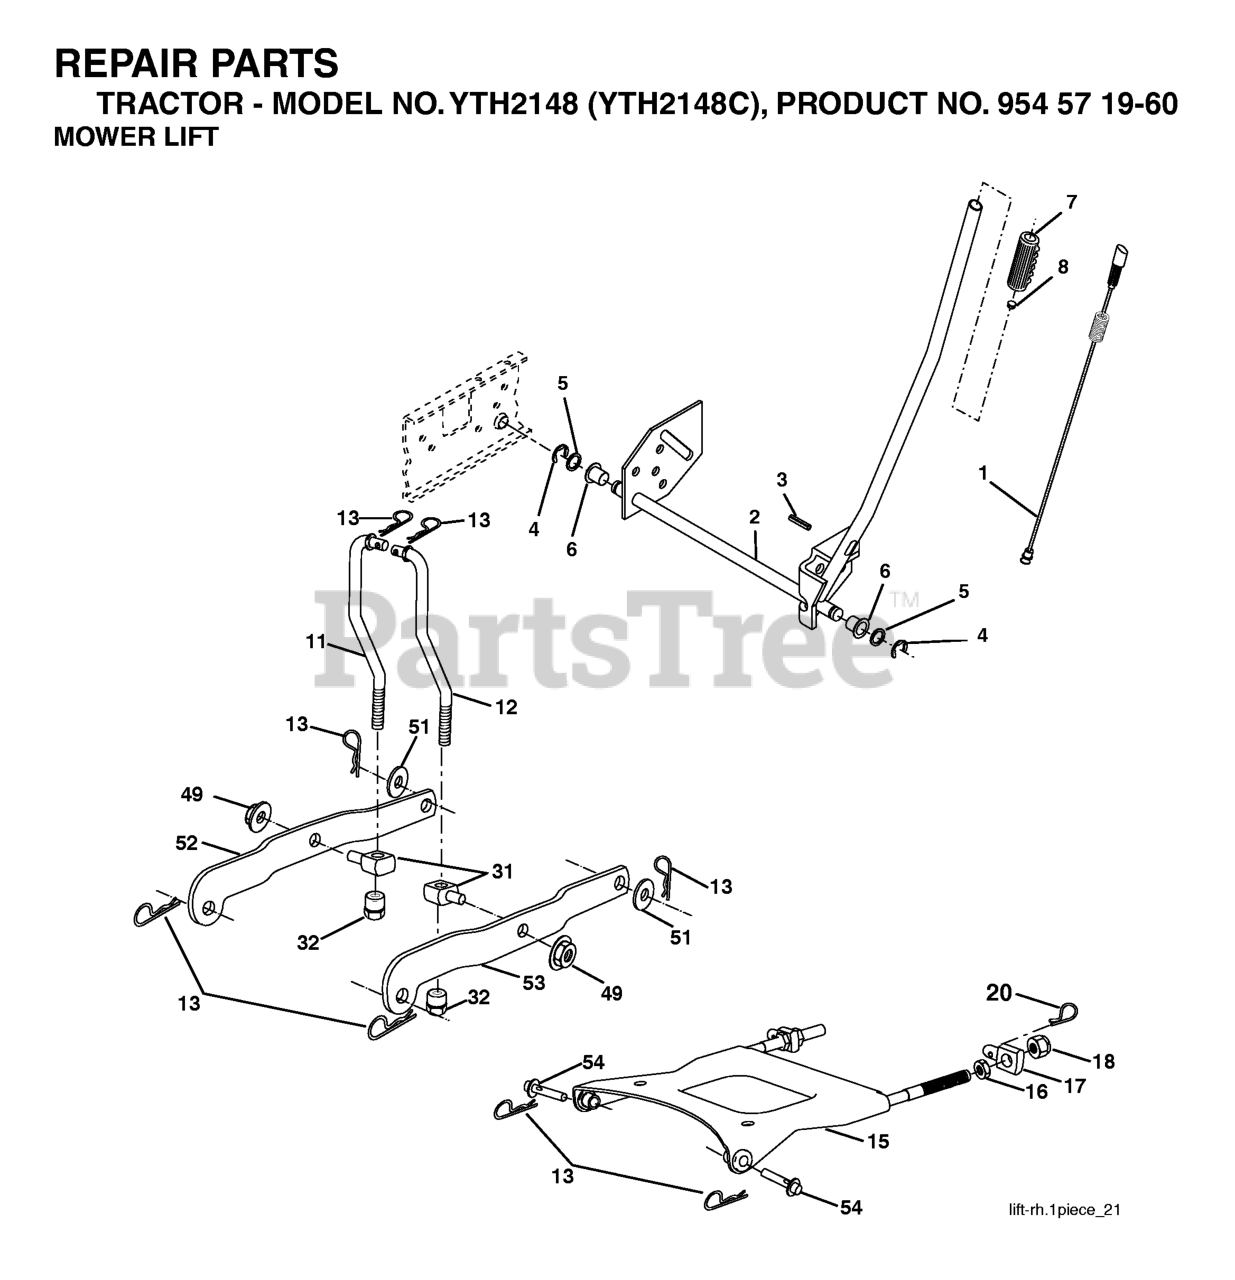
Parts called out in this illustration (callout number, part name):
1	WIRE ASM INNER W/ PLUNGER LT
2	SHAFT ASM R HANDLE
3	PIN GROOVE.
4	RETAINING RING LT
6	BEARING.NYLON
7	GRIP HANDLE
8	PLUNGER BUT KIT
11	LIFT LINK LH
12	LIFT LINK RH
13	RETAINER-SPRNG RB
15	PLATE ASM SUSP FRONT
16	NUT.HEX.JAM.1/2-13
18	NUT.LK.W/WSH.1/2.
20	SPRING RETAINER
32	NUT, LIFT LINK 7/16-20
49	NUT
51	Washer 1 17/32 X 7/8 X 16 Ga
52	ARM SUSP. REAR LH
53	ARM SUSP REAR RH
54	PIN.FLANGE
